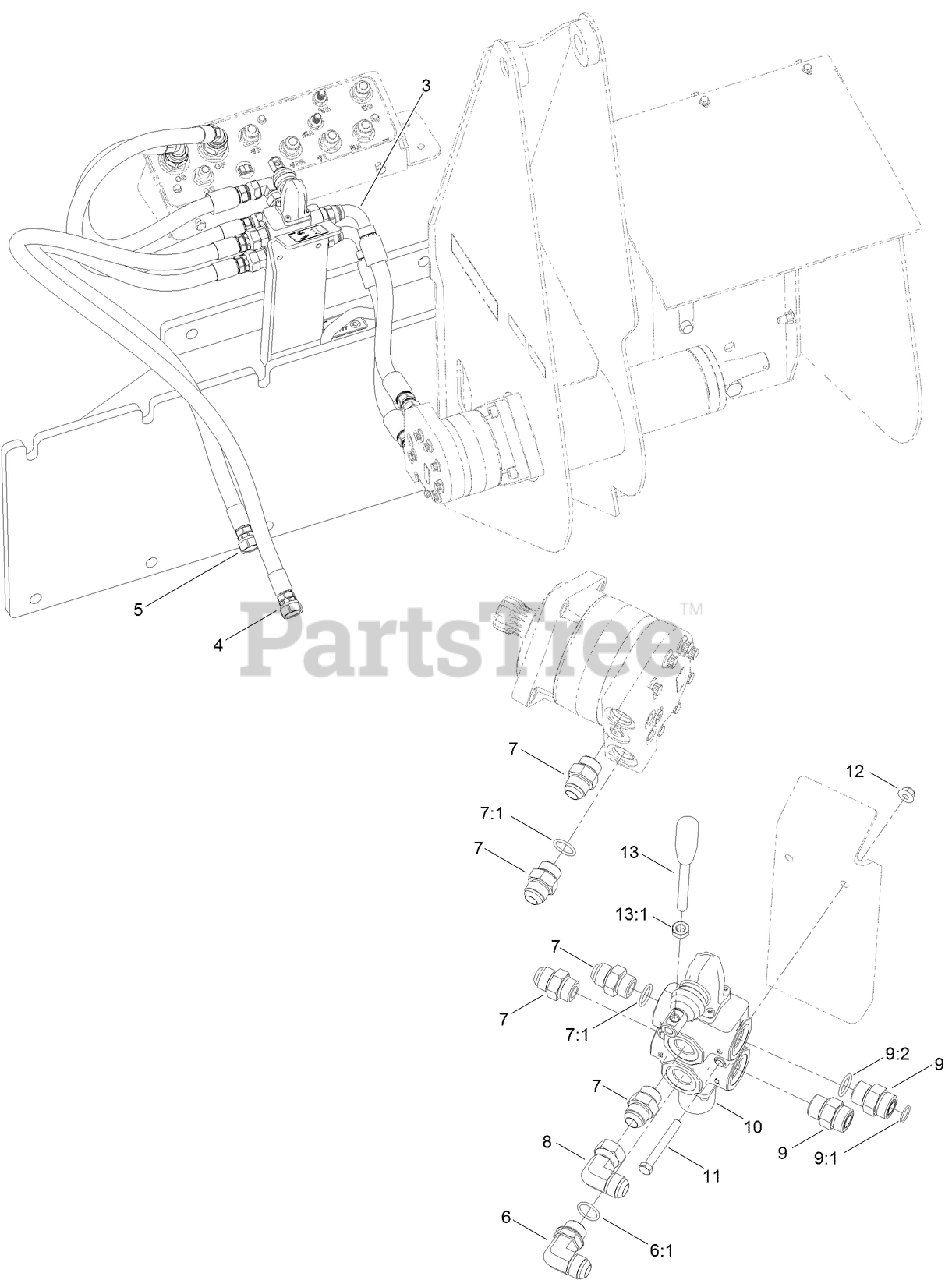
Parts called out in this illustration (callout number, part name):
3	HOSE ASM
4	HOSE ASM
5	HOSE ASM
6	FITTING-ELBOW, 90 DEG
6:1	O-RING
7	FITTING-STRAIGHT
7:1	O-RING
8	FITTING-ELBOW, 90
9	FITTING-STR
9:1	O-RING
9:2	O-RING
10	VALVE-SELECTOR
11	SCREW-HH
12	NUT-HF, NI
13	HANDLE-SELECTOR
